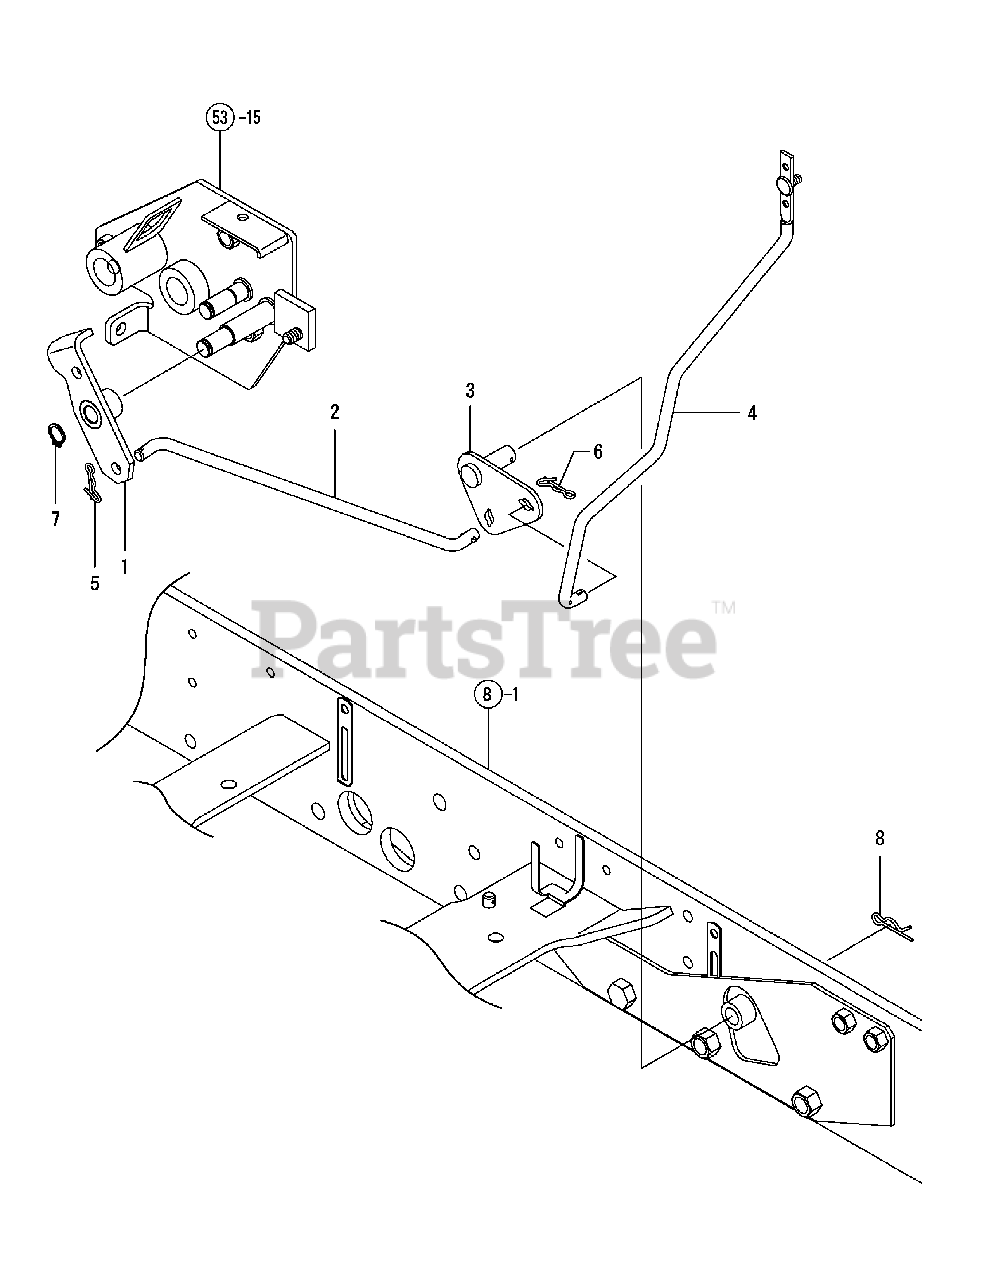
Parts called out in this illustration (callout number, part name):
1	ARM A, CRUISE CMP
3	LINK, CRUISE CMP
4	ROD B, CRUISE CMP
5	PIN 8, COME-OFF SNAP
6	PIN 8, COME-OFF SNAP
